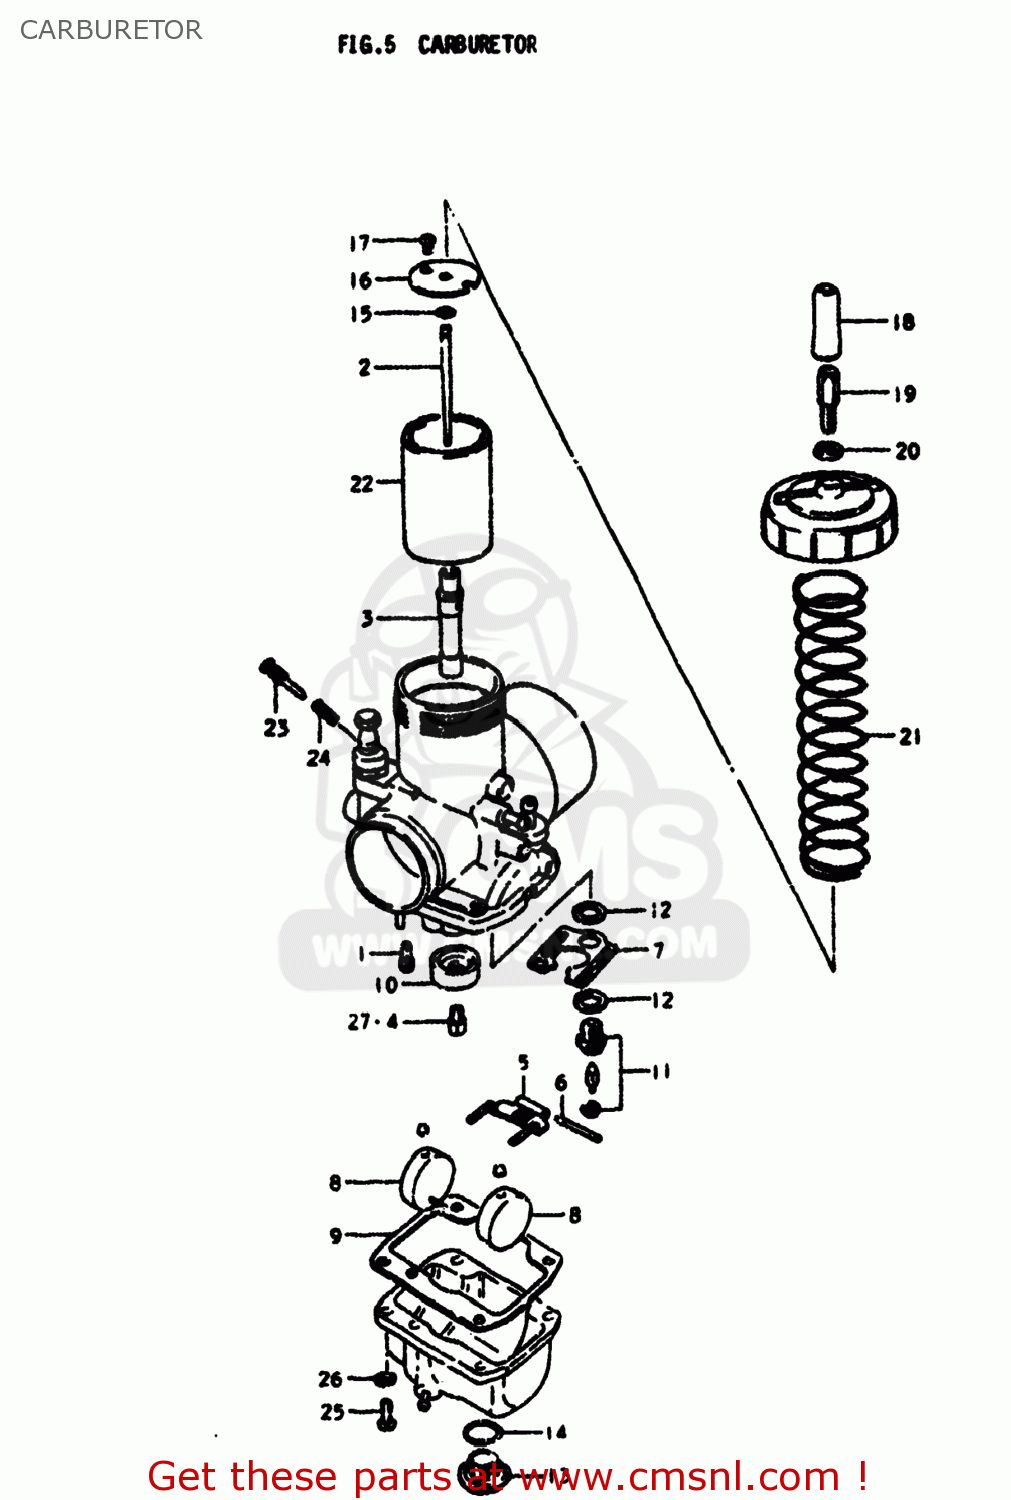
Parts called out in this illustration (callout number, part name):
1	JET,PILOT(50)
2	JET,NEEDLE(6FJ6-3)
3	JET,NEEDLE
4	JET
5	ARM,FLOAT
6	PIN,FLOAT
7	PLATE
8	FLOAT
9	GASKET,FLOAT CAHMBER (NAS)
10	RING
11	VALVE ASSEMBLY,NEEDLE
12	GASKET,MAIN JET HOLDER (NAS)
13	SCREW,GUIDE
14	O-RING
15	CLIP
16	CLIP
17	SCREW
18	CAP,CABLE ADJUSTER
19	ADJUSTER,CABLE
20	NUT
21	SPRING,THROTTLE VALVE RETURN
22	VALVE,THROTTLE
23	SCREW,PILOT AIR
24	SPRING
25	SCREW
26	LOCK WASHER
27	JET
